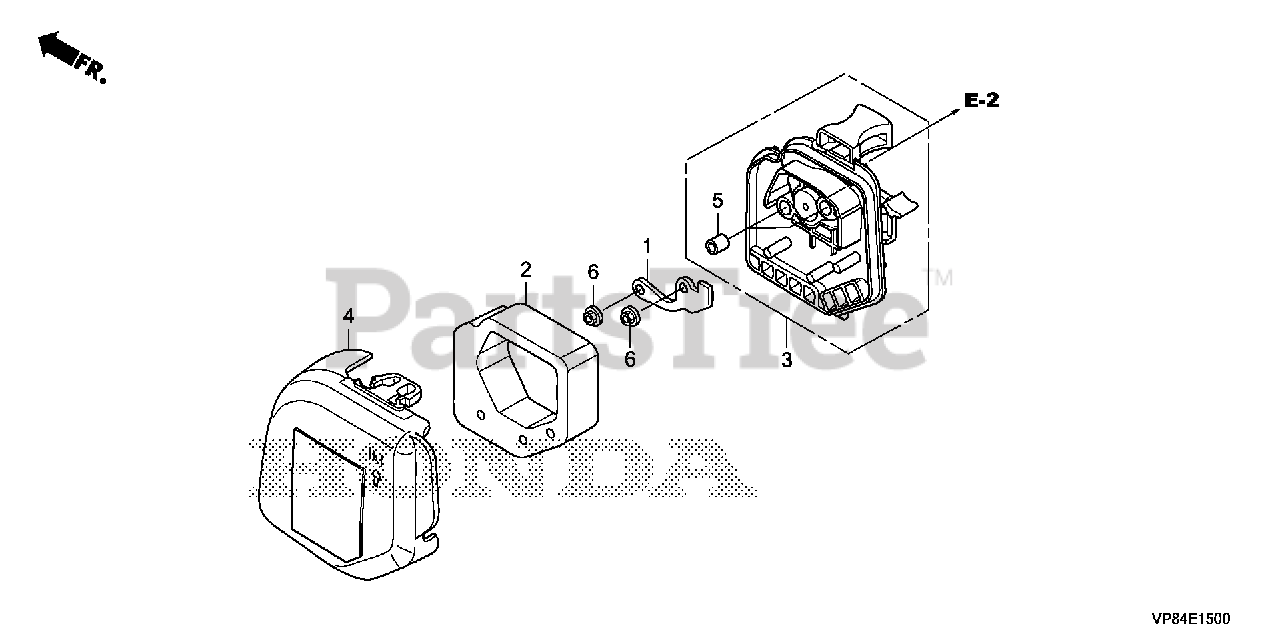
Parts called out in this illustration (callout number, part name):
1	PLATE, OIL TRAP
2	ELEMENT, AIR CLEANER
3	HOUSING, AIR CLEANER
4	COVER, AIR CLEANER
5	COLLAR, AIR CLEANER
6	NUT, FLANGE (5MM)
